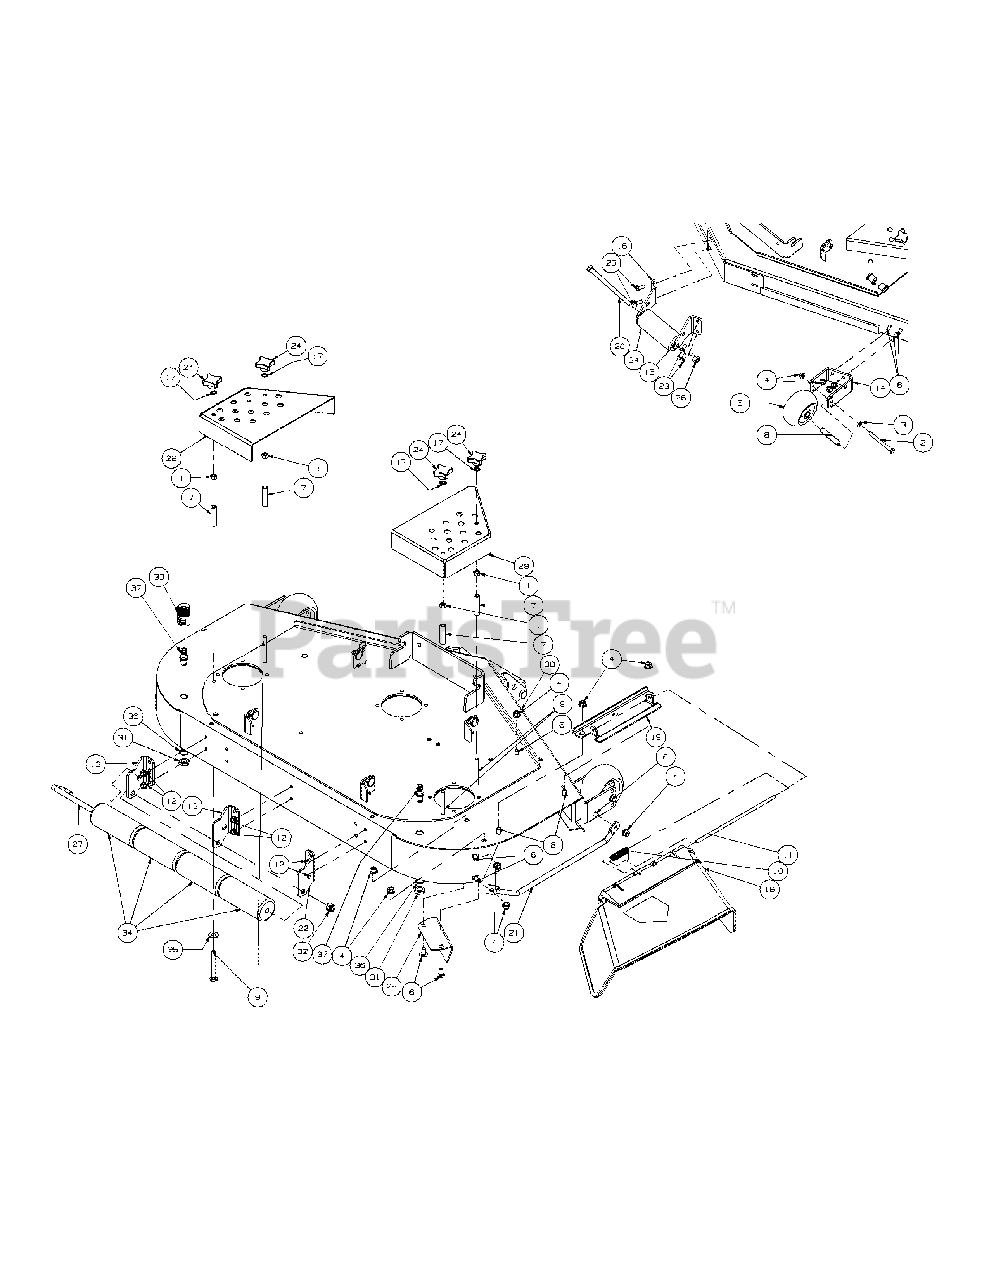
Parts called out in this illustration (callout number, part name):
1	Nut, 3/8-16, Hex
2	Hex Cap Screw, 3/8-16, 3.75
4	Hex Nut, 3/8-16 Flange Lock
5	Complete Wheel, 5.00 Dia
6	Carriage Bolt 3/8-16 x .75
8	Wheel Spacer
9	Carriage Bolt, 3/8-16 x 3.50
10	Torsion Spring
11	Chute Deflector Rod
12	Self Tapping Screw, 5/16-18 x 1/2
17	External Washer, 3/8
18	Deflector Chute
19	Deflector Chute Bracket
20	Hex Cap Screw, 1/2-20 x 7.50
21	Fabricated Deck Finger Guard
23	Self Tapping Screw, 3/8-16 x 0.875
24	Plastic Knob
25	Fabricated Deck, Chute Bracket
26	Lock Nut, Nylon Insert, 1/2-20
27	J-Hook w/ Threaded Roller
32	Hex Nut, 1/2-13, Insert Lock
33	Water Nozzle Adaptor
34	Front Roller
35	Washer, .510 x 1.00 x .060
36	Lock Washer, 17 x 23.8 x 1.95
37	Deck Water Nozzle
